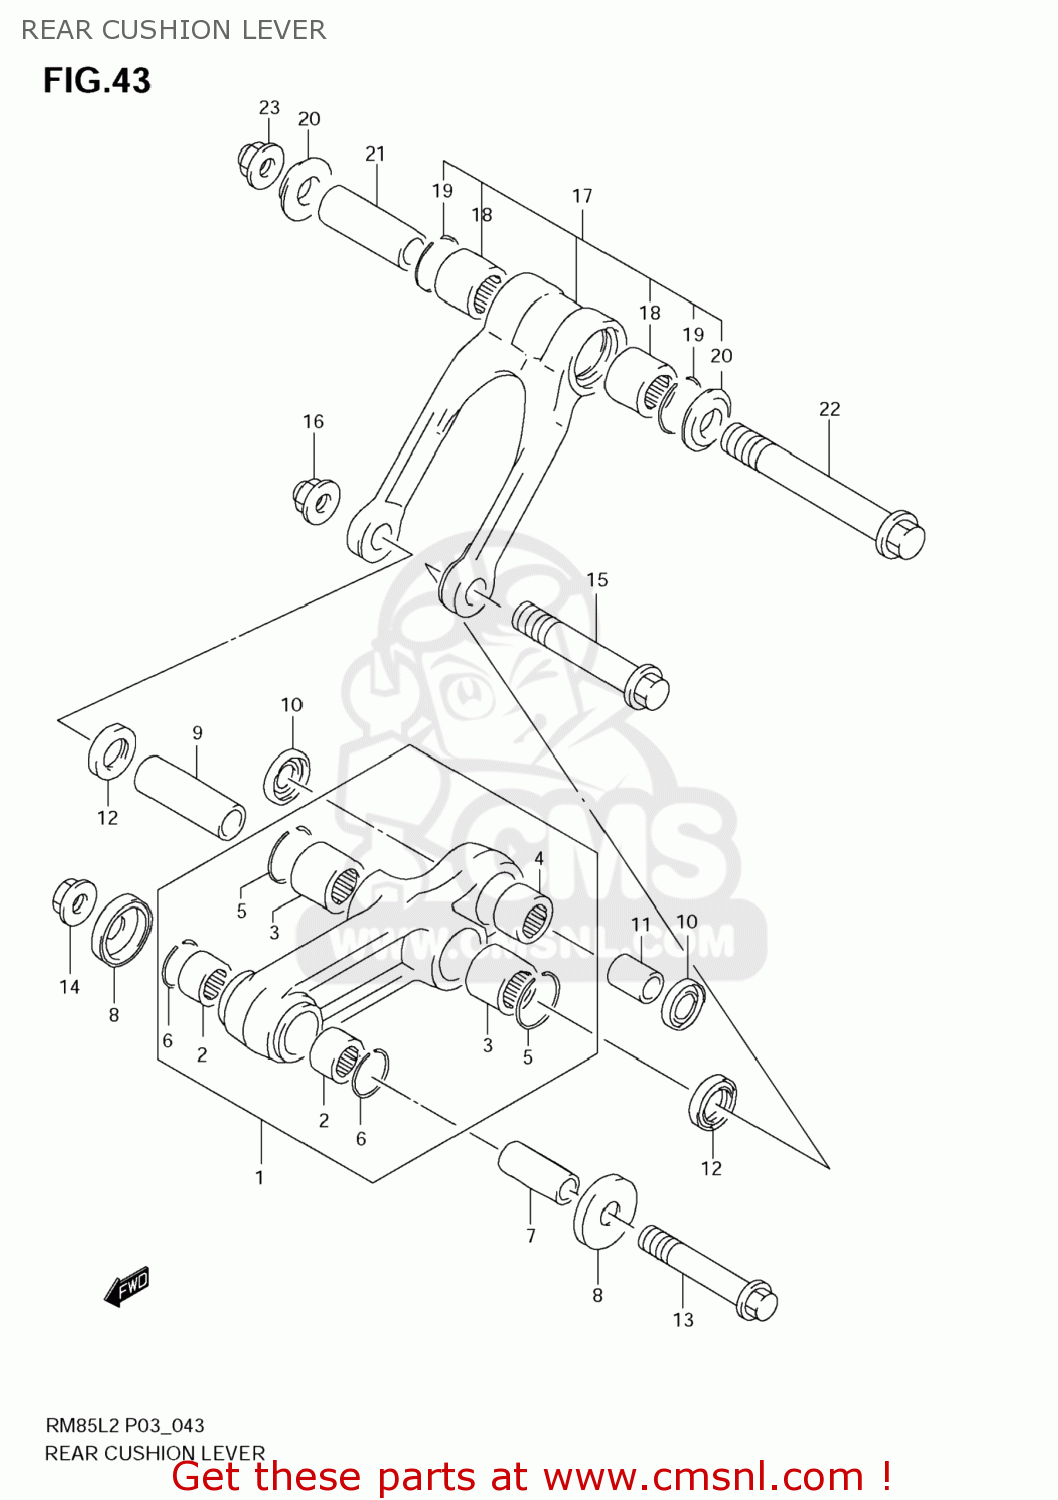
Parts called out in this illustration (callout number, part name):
1	LEVER SET,RR CUSHION
2	BEARING(14X20X12)
3	BEARING(17X24X20)
4	BEARING(20X26X12)
5	RING,STOPPER
6	CIRCLIP,PISTON PIN
7	SPACER,RR CUSHION LEVER FR
8	SEAL,RR CUSHION LEVER FR DUST
9	SPACER,RR CUSHION LEVER CTR
10	SEAL,OIL(20X26X4.5)
11	SPACER,RR CUSHION LEVER RR
12	SEAL,OIL(17X24X3)
13	BOLT,RR CUSHION LEVER FR
14	NUT
15	BOLT,RR CUSHION LEVER CTR
16	NUT
17	ROD SET,RR CUSHION LEVER
18	BEARING(17X24X20)
19	RING,STOPPER
20	SPACER,RR CUSHION ROD SIDE
21	SPACER,RR CUSHION ROD
22	BOLT,RR CUSHION ROD
23	NUT
